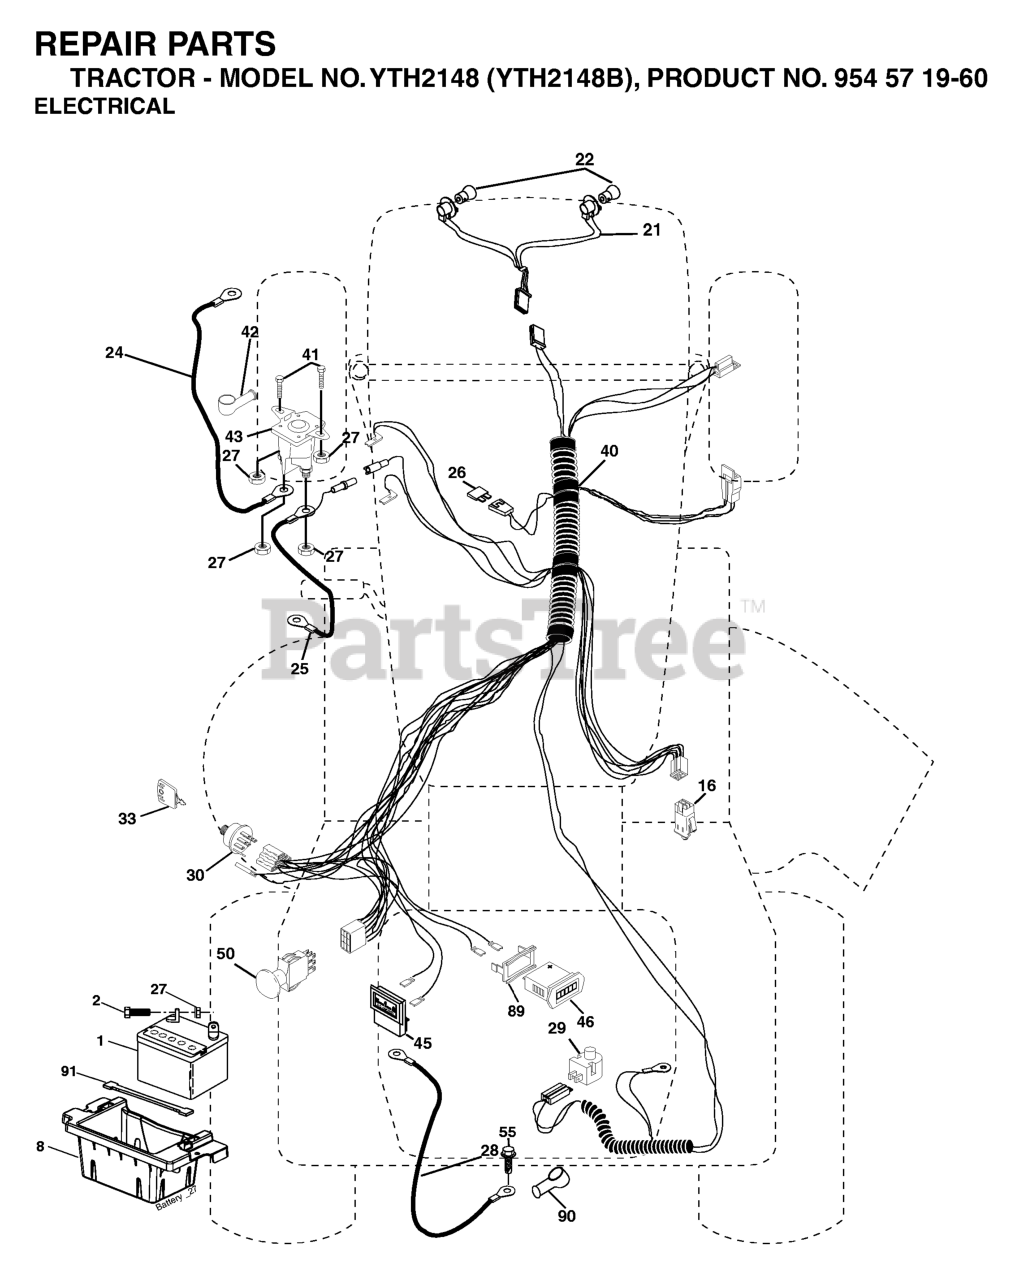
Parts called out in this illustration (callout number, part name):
1	BATTERY 12V .35 AMP
2	BOLT.HEX.1/4.X.3/4.DICHROMATE
8	BOX.BATTERY.MOUNT.FRONT.LT
10	BOLT 1/4-20 X 7.5
11	BATTERY HOLDDOWN FRONT MOUNT
12	NUT, PUSH NYLON 1/4" BATTERY
16	SWITCH INTERLOOK PUSH-IN
21	HARNESS ASSY LIGHT
24	BATTERY CABLE GT
25	CABLE BATTERY 6 GA 22" W/16W
26	FUSE 20AMP
27	NUT
28	CABLE GROUND 6 GA 21" 90T BLK
29	RP.SWITCH.PLUNGER.NC.GRAY
30	IGNITION SWITCH
33	KEY MLD GEN DELTA
40	HARNESS.IGNITION
41	BOLT
42	TERMINAL COVER
43	SOLENOID
46	HOUR METER
50	RP.PTO.SWITCH.8 TERMINAL.BLACK
55	Screw 5/16-18 x 1/2 Hex, Self Tapping 5/16-18 x 1/2
89	BRACKET SNAP-IN HOURMETER
90	COVER TERMINAL
91	STRAP.BATTERY.MOUNT.FRONT(2 2)
